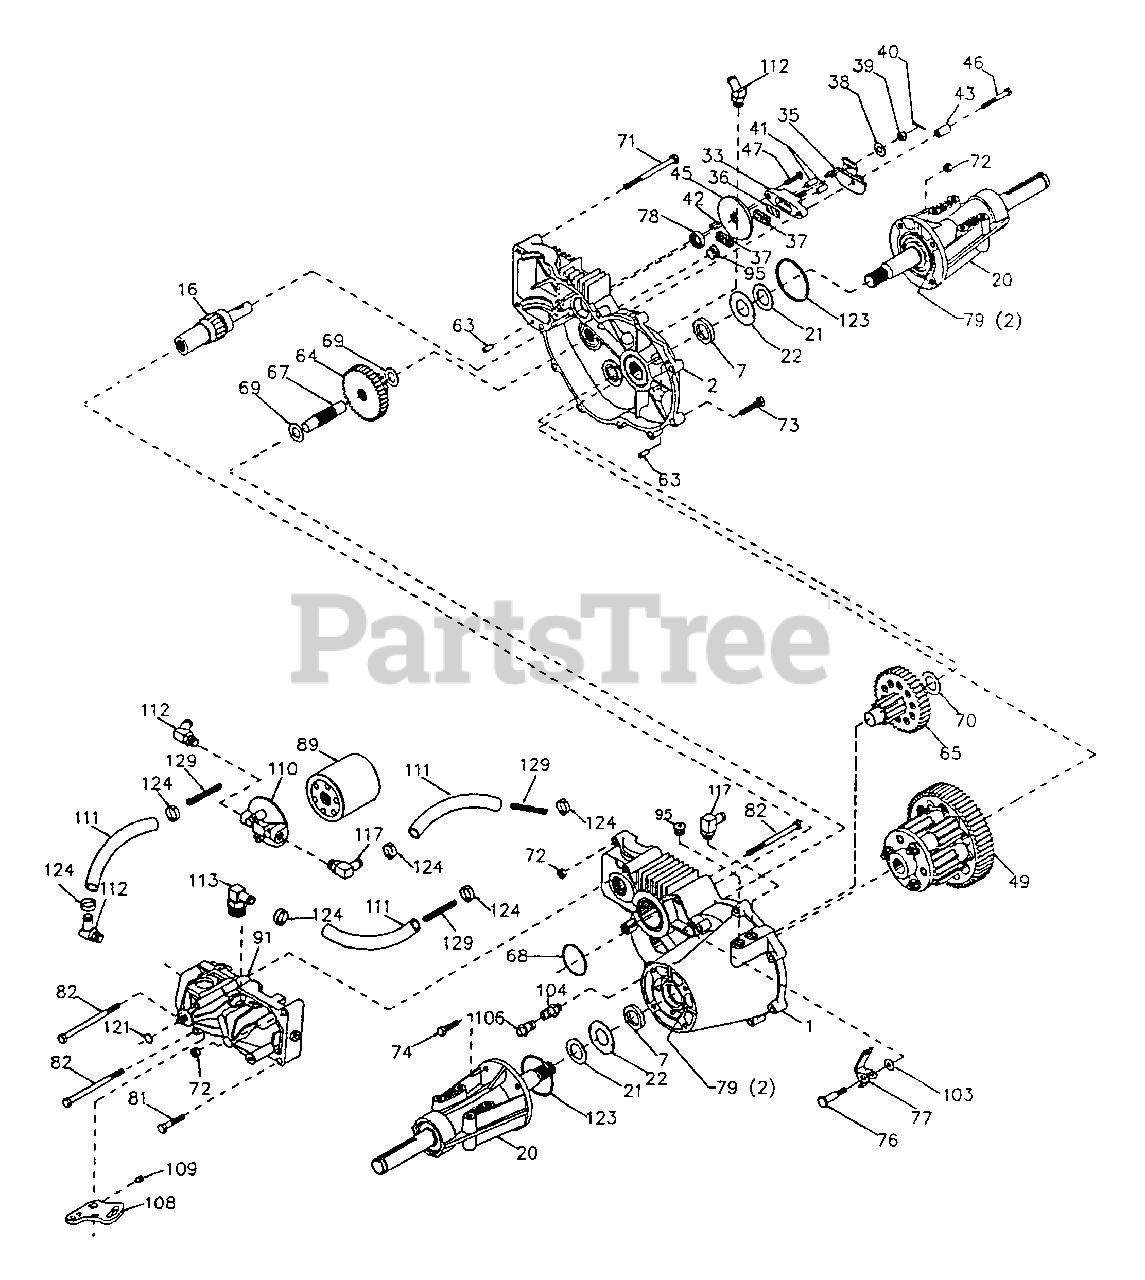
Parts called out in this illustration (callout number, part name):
1	Assembly, Housing, LH
2	Assembly, Housing, RH
7	Oil Seal .984 x 1.5 x .25
16	Brake Shaft Assembly
20	Axie Mounting Horn Assembly
21	Washer 1.0 x 1.63 x .08
22	Washer 1.0 x 2.06 x .09
33	Brake Yoke Assembly (AYP part number)
35	Brake Arm
36	Puck Plate
37	Brake Puck
38	Washer 7/8 O.D. x 7/16 x .060
39	Nut, Castle 5/16-24 (AYP part number)
40	Cotter Pin (AYP part number)
41	Brake Actuating Pin
42	Hi Pro Key
43	Spacer
45	Brake Disc
46	Bolt 1/4-20 x 1-1/2
47	Bolt 1/4-20 x 1
49	Differential Assembly
63	Dowel Pin
64	Reduction Gear, 14 Teeth to 38 Teeth
65	Final Drive Pinion Assembly
67	Jackshaft
68	O-Ring
69	Washer 5/8 X 1-5/32
70	Washer 7/8 X 1-1/2
71	Bolt, Hex 5/16-18 x 3.5
72	Locknut, Hex 5/16-18
73	Bolt, Hex 5/16-18 x 1-1/2
74	Hex Cap Screw 5/16-18 x 1
76	Shoulder Bolt
77	Freewheel Actuating Arm
78	Oil Seal .625 x 1.0 x .25
79	Grease (AYP part number)
81	Bolt, Hex 5/16-18 x 1-3/4
82	Bolt 5/16-18 x 4-1/2
89	Filter, Spin On (AYP part number)
91	Pump, BDU-10L-122
95	Plug, Straight Thread
96	60ø 7/18 SAE x 5/16 Fitting
103	Washer
104	Vent Cap Assembly
106	Fitting O-Ring Assembly (Outside vendor part number)
108	Control Arm
109	Set Screw
110	Filter Head
111	Hose 1/2"
112	Fitting, 1/2" Beaded 90ø 7/8 SAE
113	Fitting, 1/2" Beaded 60ø 9/16
117	Fitting, 1/2" Beaded 90ø 9/16
123	O Ring
124	Pinch Clamp
129	Spring, Long
